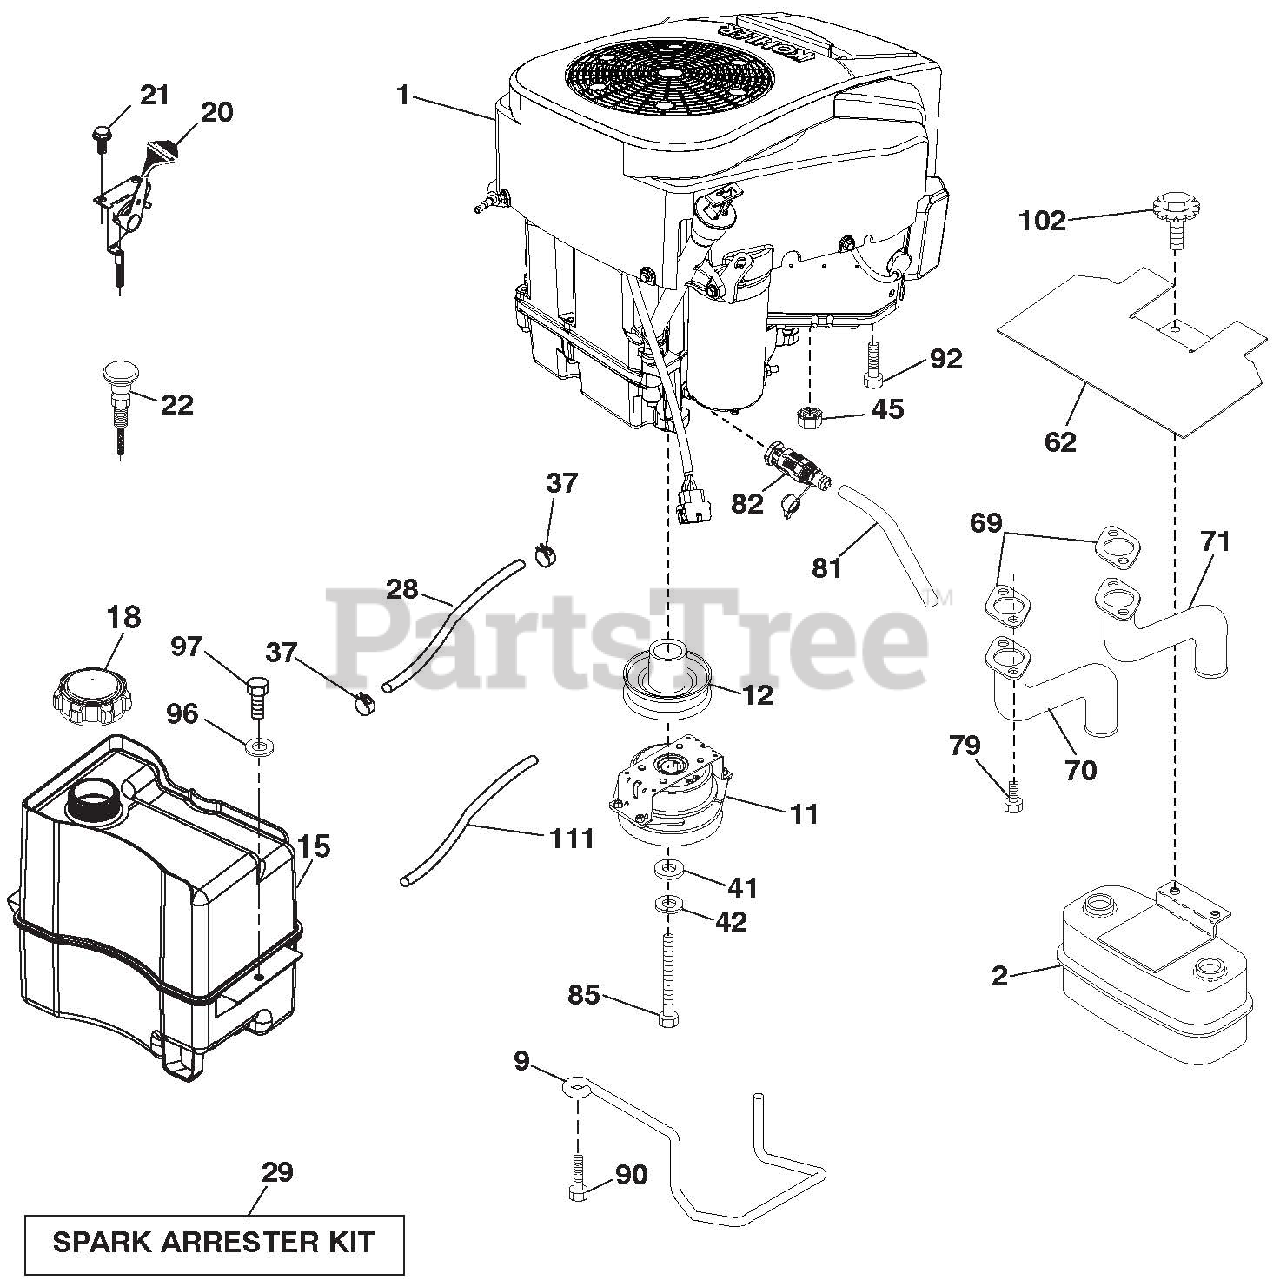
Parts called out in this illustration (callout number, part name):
1	KOHLER.ENGINE
2	MUFFLER ASM.
9	KEEPER.BELT.ENGINE
11	ELECTRIC CLUTCH
12	PULLEY.ENGINE.TUFFTORQE.1"CRK.
15	TANK.FUEL.2.5.GAL.
18	CAP.FUEL
20	CONTROL.THROTTLE
22	CONTROL CHOKE
28	LINE.FUEL.22"FRONT.EMIS.CA.LP
29	KIT.SPARK ARRESTOR(392390 B&S)
37	CLAMP.HOSE.BLK.
41	WASHER.1-1/2 ODX15/32 IDX.250
42	WASHER.LOCK.HVY HLCL.SPR.7/16
45	Nut, Keps Hex 1/4-20 unc
62	SHIELD.HEAT.MUFFLER.
70	EXHAUST TUBE LH
71	EXHAUST TUBE RH
79	SCREW.SOCKET HD.5/16-18 X .75
81	TUBE.DRAIN.OIL.EASY
82	VALVE OIL DRAIN
85	BOLT.HEX.7/16-20 X 3.75 X GR.
90	SCREW.3/8-16X1.SMGML.TAP/R.BLK
92	SCREW.3/8-16 X 1.SMGML.TAP/R
96	WASHER.9/32 X 7/8 X 16GA.
97	SCREW.HEXWSH.THDROL.1/4-20X3/4
102	SCREW.5/16-18X3/4.SMGML.TAP/BL
111	PURGE.LINE.CARB
